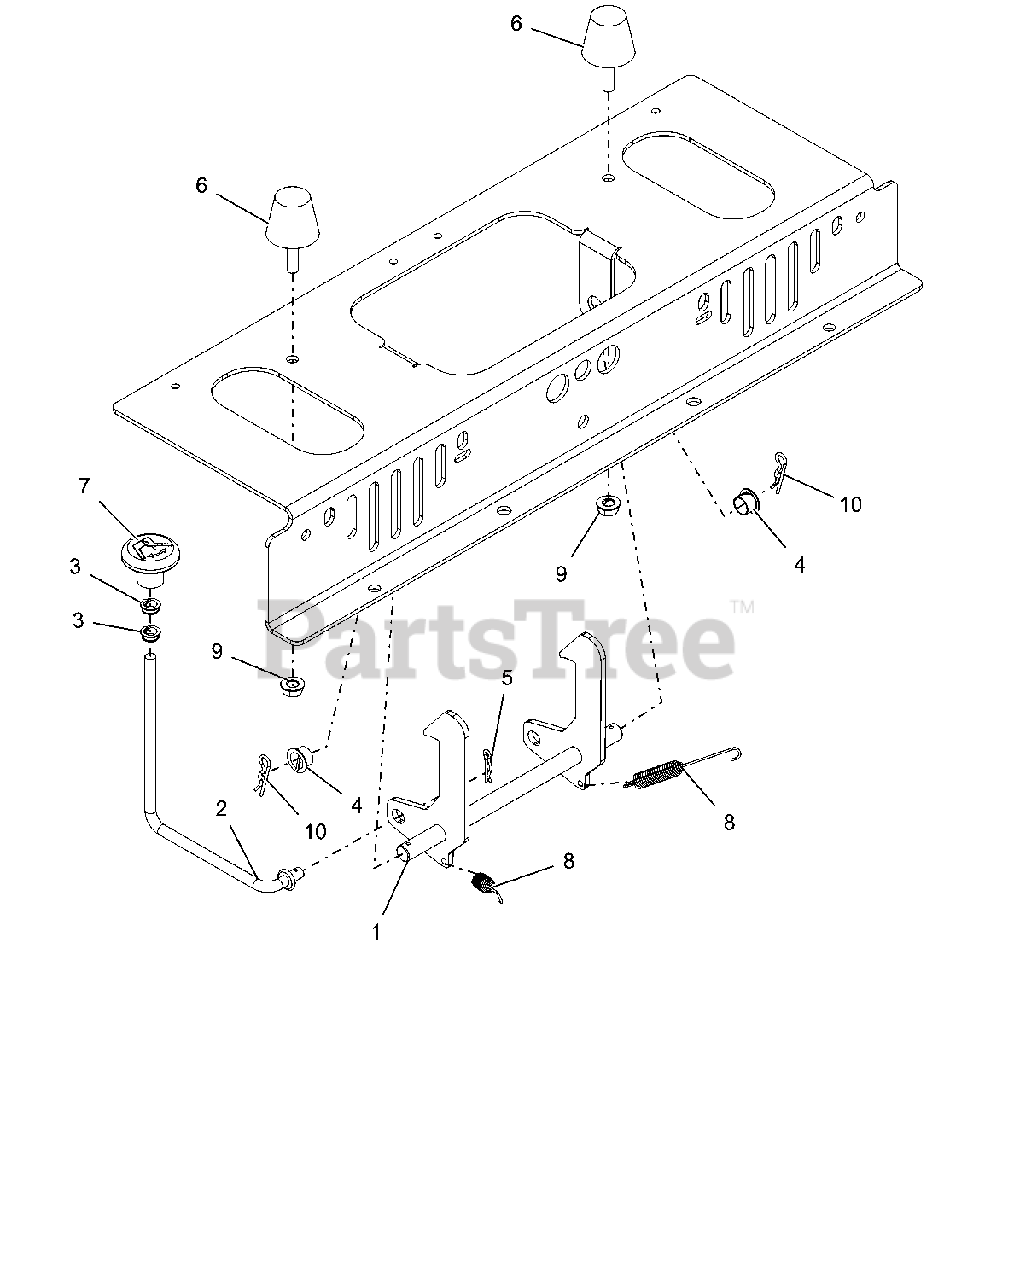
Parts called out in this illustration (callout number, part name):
1	SEAT LATCH WLDMT - LOW FILM
2	LINKAGE, SEAT RELEASE
3	BUSHING, POLYLINER-.38 SNAPIN
4	BUSHING, POLYLINER-.50 SPLIT
5	PIN-HAIR, ENDRIES #25 YWZC
6	BUMPER,STUD MOUNTED CONE SHAPE
7	KNOB, PUSH/PULL
8	SG-TENS .043X.44X3.31 WLD 5.8
9	NUT-SPNLK-FLG .312-18 YWZC
10	PIN-HAIR INT .08X.38X1.42 YWZC
